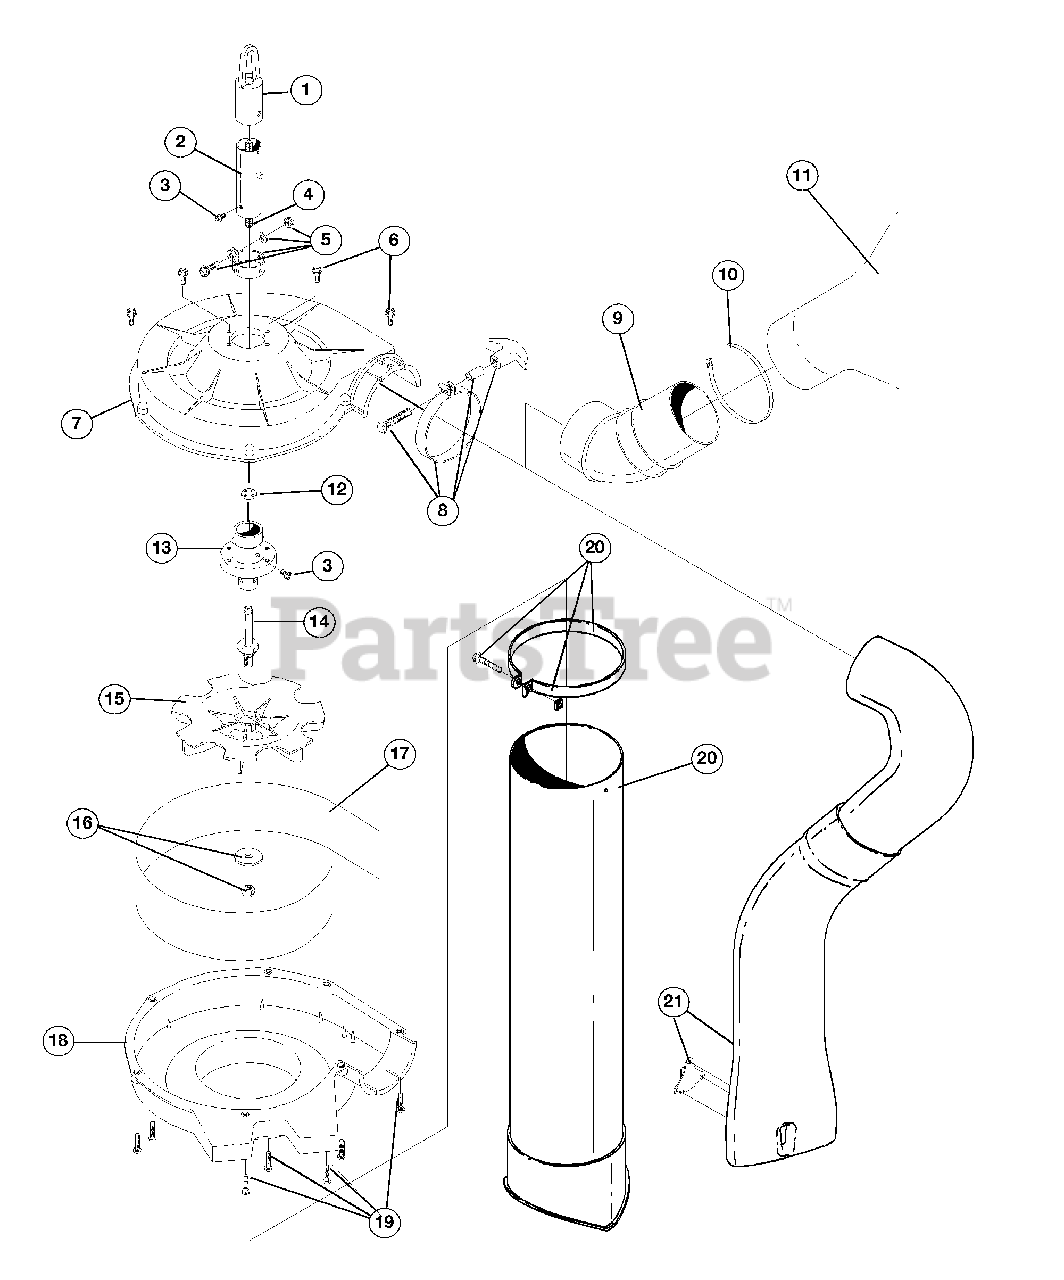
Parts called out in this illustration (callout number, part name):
1	Hanger
2	Boom Assembly
3	Anti-Rotation Screw
4	Drive Shaft Assembly
5	Lower Clamp Assembly
6	Mounting Screw
7	Upper Housing
8	Clamp Assembly
9	Adapter
11	Vacuum Bag Assembly
12	Palnut
13	Bushing Housing Assembly
14	Impeller Shaft
15	Impeller
16	Nut and Washer Assembly
18	Lower Housing
19	Mounting Screw
20	Vacuum Tube Assembly
21	Blower Tube Assembly
